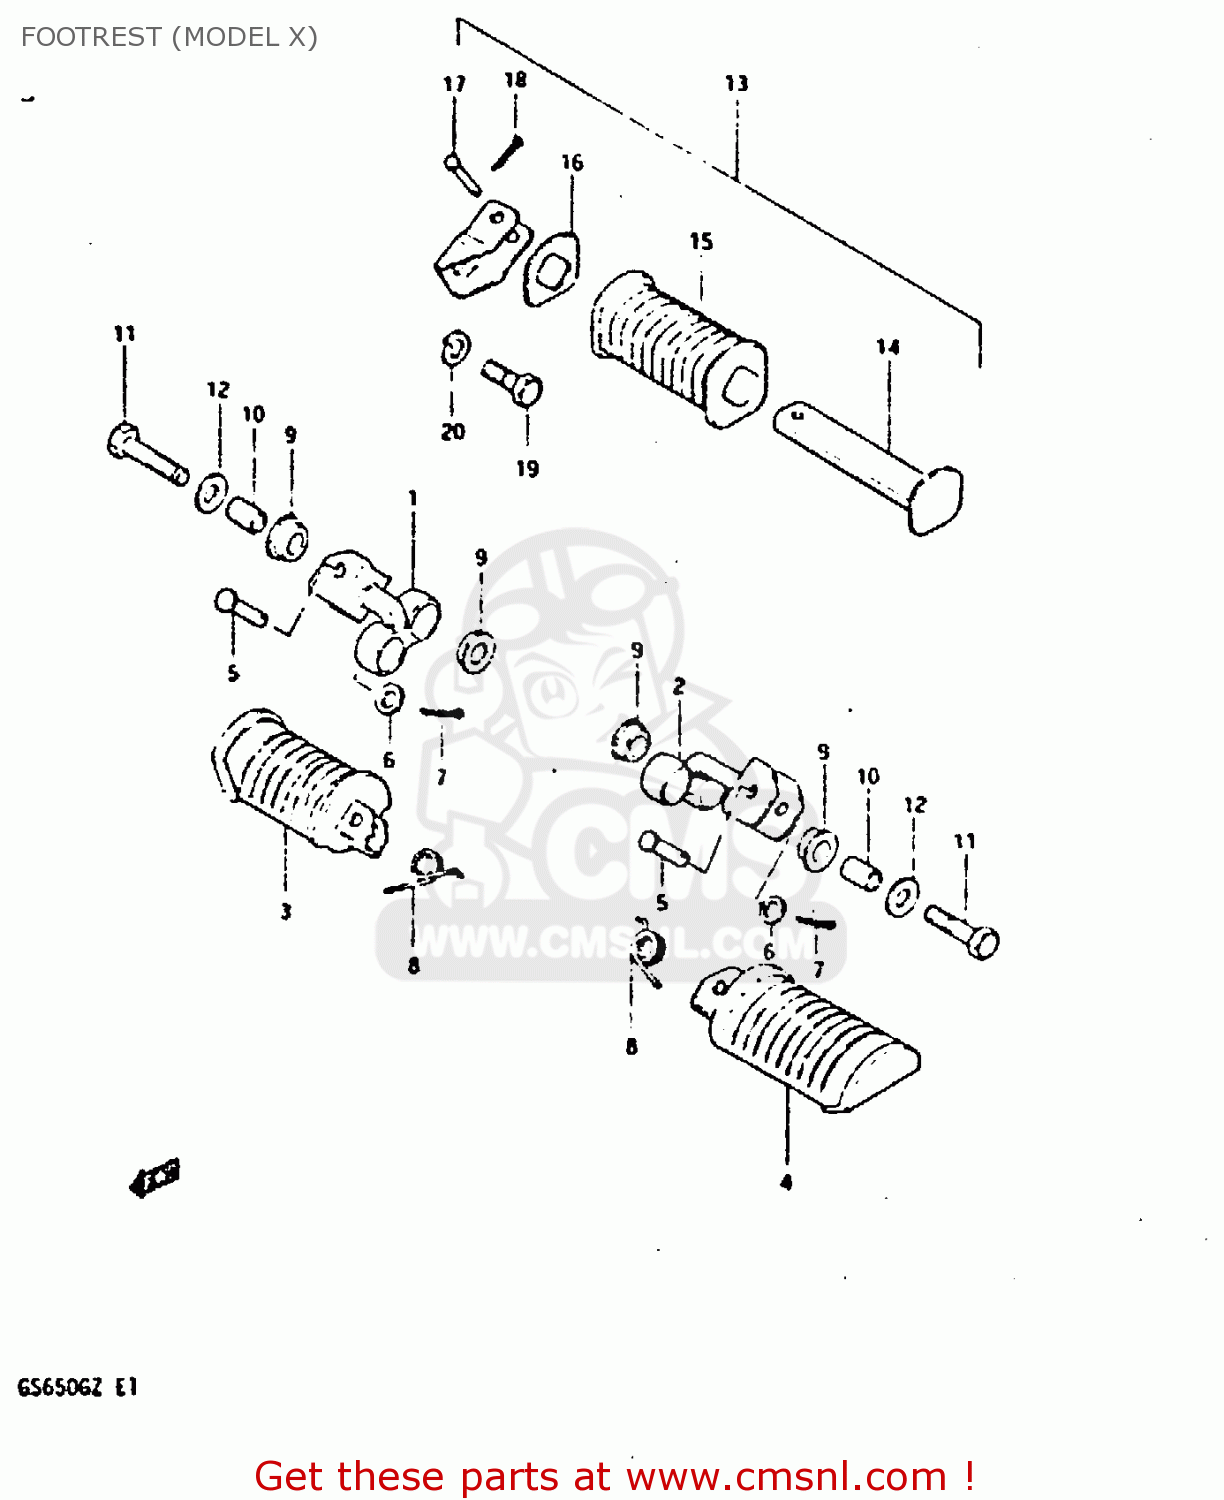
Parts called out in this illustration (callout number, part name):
1	BAR, FOOTREST RH (BLACK)
2	BAR, FOOTREST LH (BLACK)
3	RUBBER,FR FOOT
4	RUBBER, LH
5	PIN
6	WASHER
7	PIN
8	SPRING
9	BUSH
10	SPACER (10.2X14X20)
11	BOLT 10X40
12	WASHER(10.2X28X2.3)
13	FOOTREST ASSEMBLY,REAR,LEFT
14	BAR,REAR FOOTREST,LEFT
15	RUBBER,PILLION FOOTREST
16	WASHER,PILLION FOOTREST RUBBER
17	PIN
18	PIN
19	BOLT 10X20
20	LOCK WASHER
